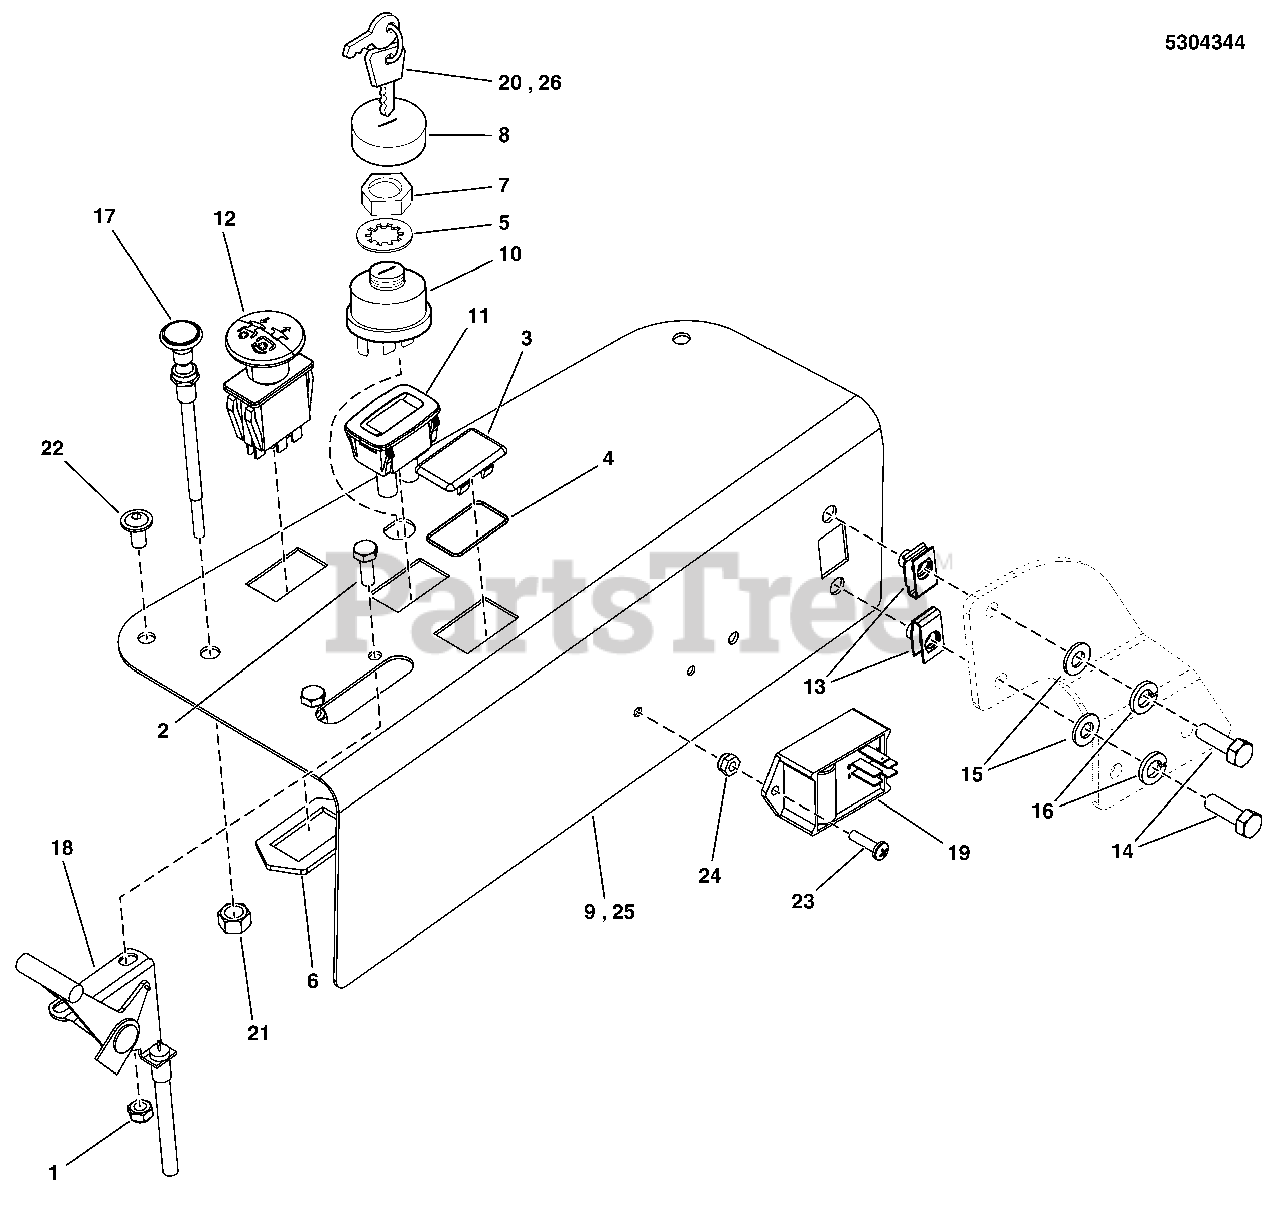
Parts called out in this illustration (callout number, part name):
1	NUT, Hex, Nylon Lock, 1/4-20
2	CAPSCREW, Hex Head, 1/4-20 x 3/4 (stiffener to top of cover)
3	PLUG, Hole, Electric Lift (Hydro models only)
4	O-RING, 7/8" ID X 1/16" W
5	LOCKWASHER, Internal Tooth, 5/8 Thin
6	RING, SWITCH RETAINER, PTO
7	NUT, Hex Flange, 5/8-32 IGN SW DIE CAST
8	COVER, Ignition Switch
9	PLATE, CONTROL PANEL, CONTENDER
10	SWITCH ASSEMBLY, Ignition Indak No Keys/Hdwr
11	HOUR METER, ASSEMBLE
12	SWITCH, PTO Push/Pull, Yel Knob w/Symbols, 8 Terminal
13	CLIP, BODY , 5/16-18 FOR 7 GA.
14	CAPSCREW, Hex Head, 5/16-18 X 1
15	WASHER, 5/16
16	WASHER, Flat
17	CABLE, CHOKE CONTROL, 51 (Z)
18	CABLE, Throttle Control, 40"
19	MODULE, TIME DELAY
20	KEYS, Ignition
21	NUT, 3/8-24 HEX JAM (SV)
22	SCREW, ALLEN HEAD 1/4-20 X .500 ZINC PHOS
23	SCREW, #10-24 X 3/4", ROUND PHILLIPS
24	NUT, Nylock, #10-24, GR2
25	PLATE, CONTROL PANEL, S550 - BLK
26	KEYS, Ignition
